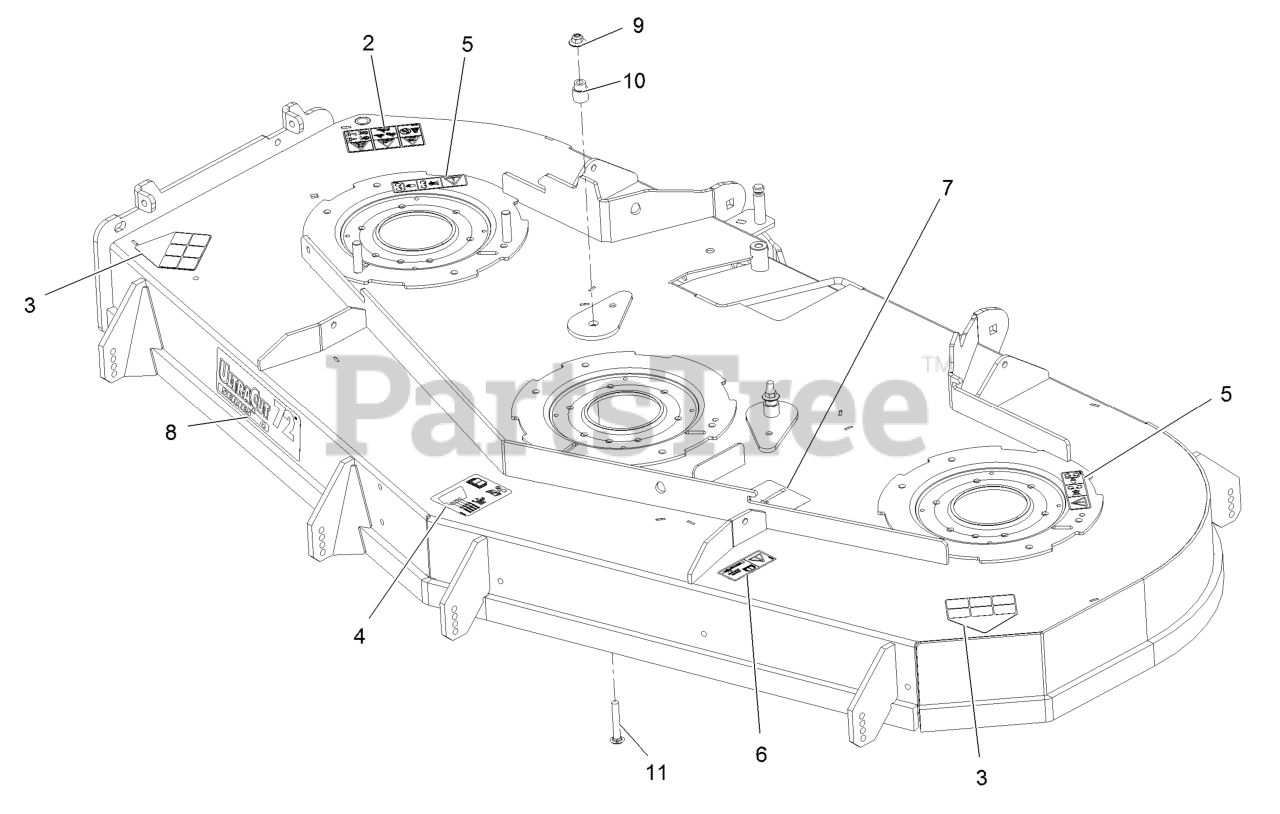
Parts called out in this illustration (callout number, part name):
2	DECAL-DANGER
3	DECAL-DANGER
4	DECAL-ROLLER, ANTI-SCALP
5	DECAL-COVER, MISSING
6	DECAL-BOLT TORQUE
7	DECAL-BELT ROUTING
8	DECAL,ULTRACUT 72 SERIES
9	Nut-Nyloc 3/8-16 Flg
10	BUSHING-IDLER
11	SCREW-CARR
